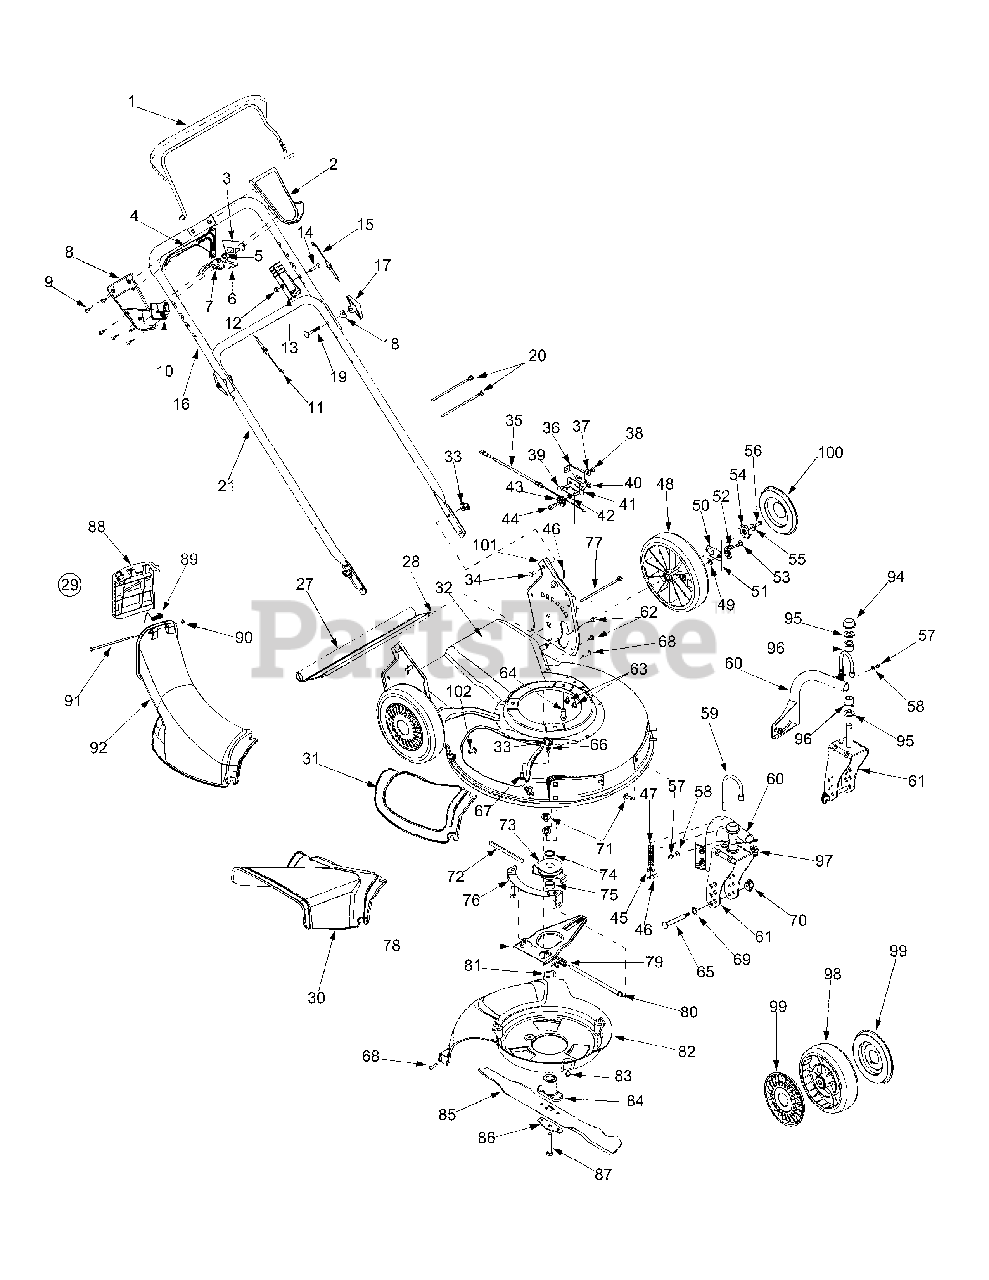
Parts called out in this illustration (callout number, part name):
1	Control Handle
2	Upper Control Housing
3	6 Spd. Rack Cable Bracket
4	Control Lever
5	Gear Insert
6	Shift Lever Spring
7	6 Speed Shift Lever
8	Lower Control Housing
9	C Sunk Tap Screw #10 x.75 Lg
10	Cable Mounting Cap
11	Drive Cable 51.0
12	Top Lock Nut 1/4-20
13	Control Housing
14	Oval C-Sunk Screw
15	Control Cable 49"
16	Upper Handle
17	Wing Nut
18	Saddle Washer.320 ID x.830 OD
19	Carriage Bolt 5/16-18 x 2.0
20	Cable Tie
27	Trail Shield
28	Trail Shield Wire
29	Chute Assembly
30	Side-Discharge Chute
31	Mulch Cover
34	Carriage Bolt 1/4-20 x.75
35	6 Speed Cable
36	Cable Adjustment Bracket
37	Bell Washer.265 ID x.75 OD
38	Hex Nut 1/4-20
39	Carriage Screw 1/4-20 x.50
40	Hex Nut 1/4-28
41	Cable Mounting Bracket
42	Lock Washer 1/4
43	Cable Roller
44	Shoulder Screw.375 ID x 1/4-14
45	Flat Washer.330 ID x.630 OD
46	Cotter Pin
47	Compression Spring
48	Wheel 9 x 2.125
49	Top Lock Tab Weld Nut 1/4-20
50	Ratchet Pawl Plate
51	Plastic Spring Ratchet
52	Pawl RH
52	Pawl LH
53	Shld Screw.340 ID x.285 OD
54	Wheel Rachet
55	Bell Washer.265 ID x.75 OD
56	Hex Cap Screw 1/4-20 x.620
57	Grease Fitting
58	Flat Washer.203 ID x.403 OD
59	Wheel Pin Lock
62	Screw 1/4-14 x.500
63	Screw 1/4-20 x.625
64	Hex Washer Screw 3/8-16 x 1.0
65	Caster Axle
66	Push Nut.25ID x.50OD
67	Carriage Screw 1/4-20 x.75
68	Screw #12-16 x 1.00
69	Wave Washer.531 ID x.781 OD
70	Wing Nut
71	Carriage Bolt 5/16-18 x.62
72	Belt 3/8 x 39.24
73	Pulley Assembly
74	Sleeve Spacer.88 ID x 1.13 OD
75	Sleeve Spacer.88 ID x 1.00 OD
77	Cable Tie
80	Pivot Shaft
81	Wave Washer 1.38 ID x.88 OD
83	Screw 1/4-20 x 3.75
84	Blade Adapter
85	21" Mulching Blade
86	Blade Bell Support
87	Hex Bolt 3/8-24 x 2.5
88	Chute Door
89	Torsion Spring
90	Push Cap
91	Pivot Rod
92	Discharge Chute
94	Push Cap
95	Flat Washer.640 ID x 1.12 OD
96	Flange Bearing
97	Flange Lock Nut 5/16-18
98	Wheel 7 x 2
99	Hubcap - Spoke w/ Hole
100	Hubcap - Radial Spoke
